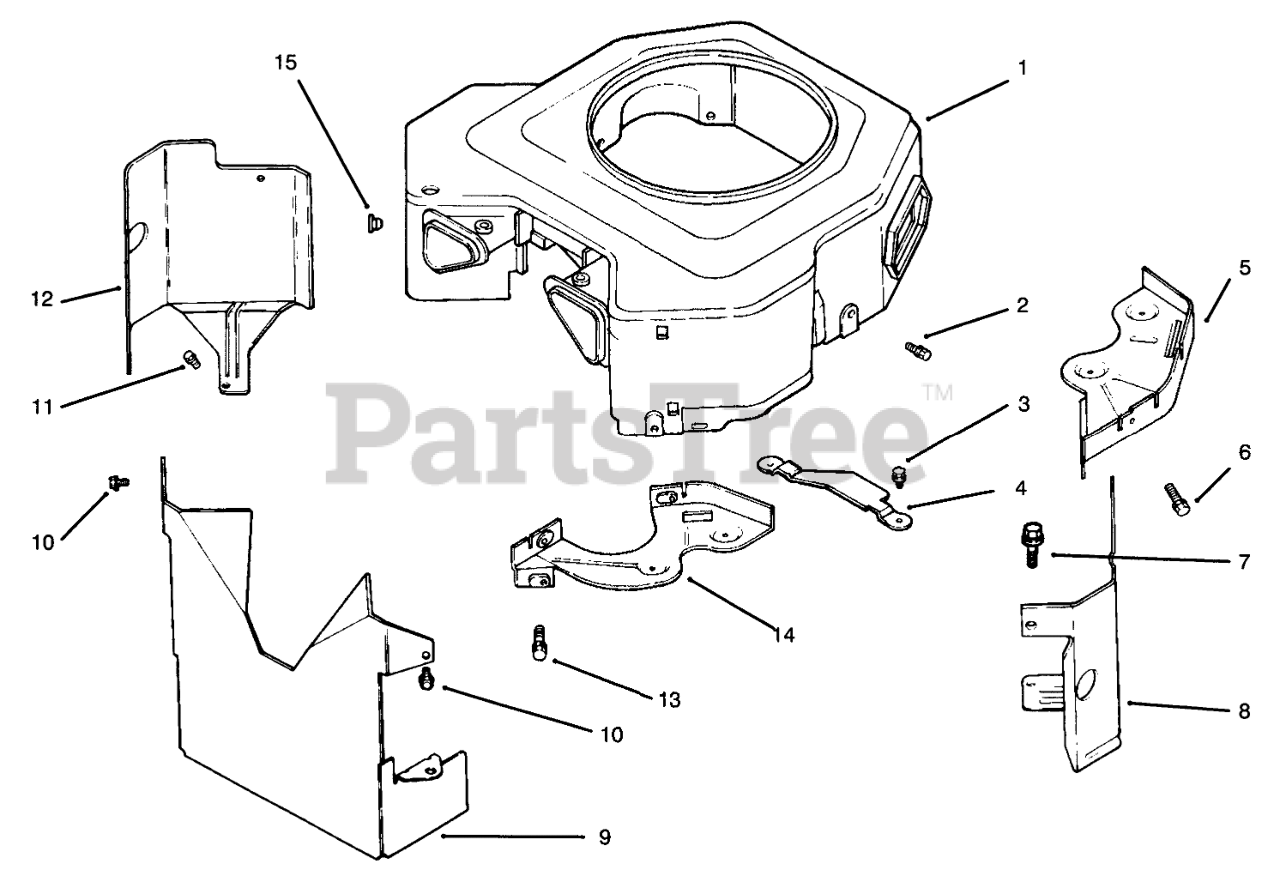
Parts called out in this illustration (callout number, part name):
1	Housing-Blower
2	Screw
3	Screw
4	Guard-Flywheel
5	Plate-Backing #2 side
6	Screw
7	Screw
8	Baffle Cylinder #2 Side
9	Baffle-Valley
10	Screw
12	Baffle Cyl. Barrel #1 Side
13	Screw
14	Plate-Backing #1
15	Nut INC W/Blower Housing
